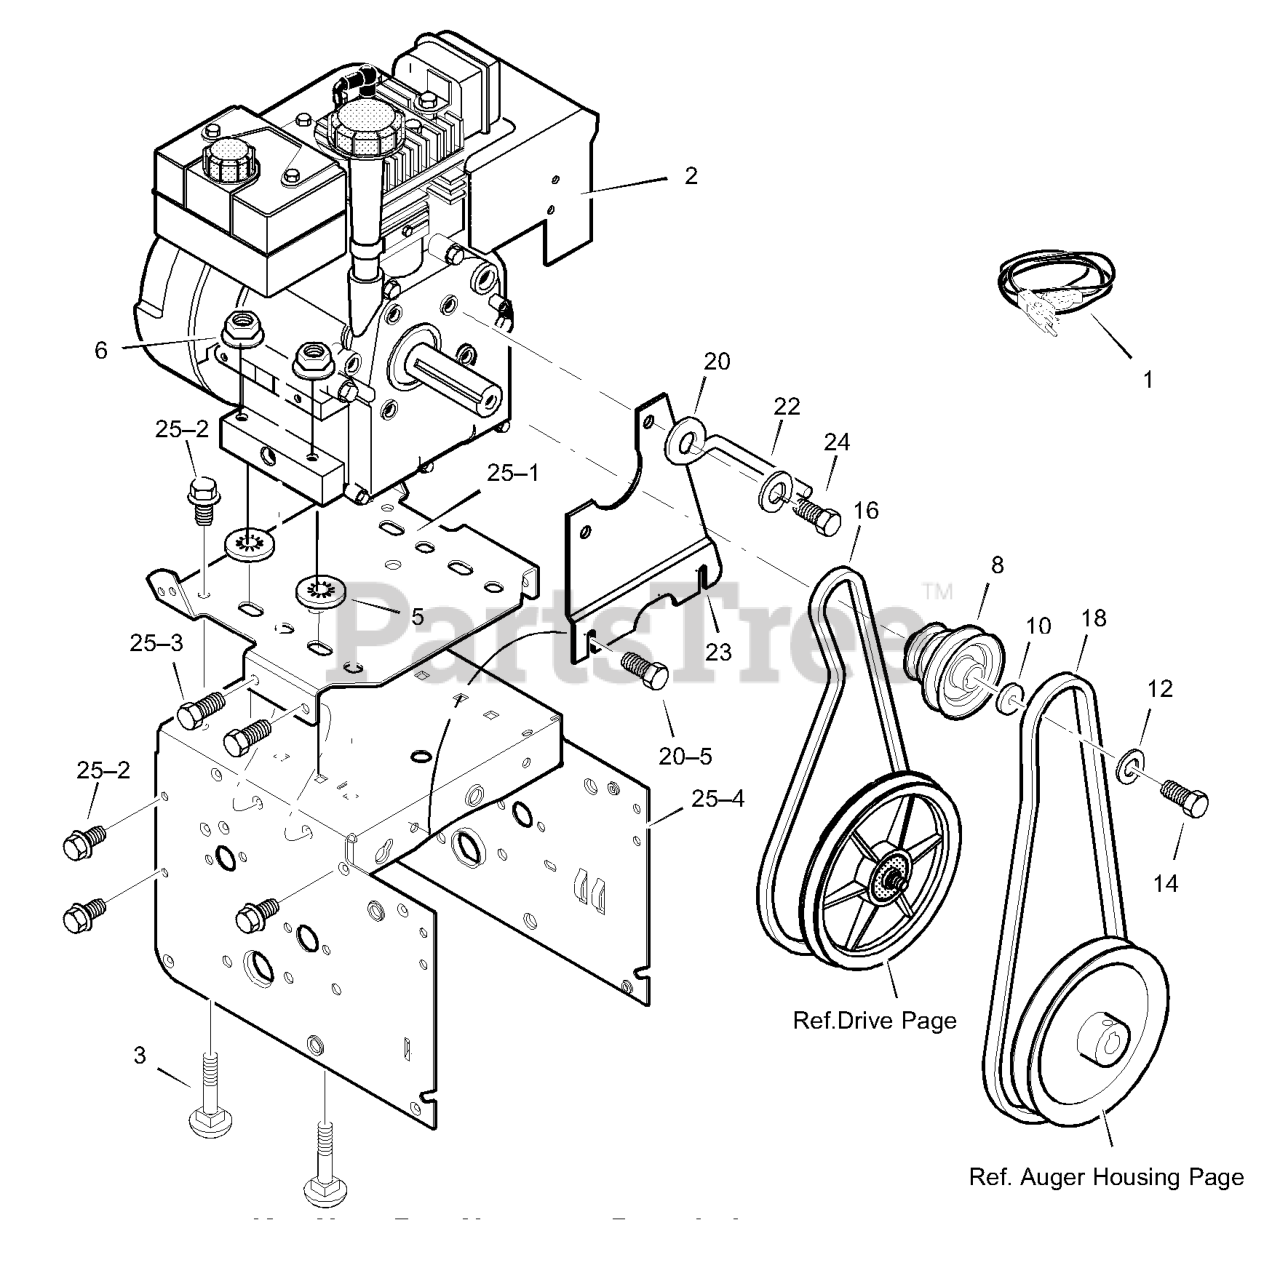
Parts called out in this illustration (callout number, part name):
1	CORD, STARTER MOTOR 220V
2	ENGINE
3	BOLT, CARRIAGE 5/16-18
5	RETAINER, PUSH
6	NUT, HEX 5/16-18
8	PULLEY, ENGINE
10	WASHER
12	WASHER .38ID
14	SCREW, 3/8-24 x 1.00
16	BELT, V 3L 33.13LG
18	BELT, V 4L 38.1MF16" 5-10
20	GUIDE, BELT
22	WASHER, SPTLK .31X.58X.08
23	PLATE, ANTI VIBRATION
24	SCREW, 5/16-24 x 1.00
25	FRAME ASSEMBLY
25-1	PLATE, ENGINE MOUNT
25-2	SCREW, TAP 1/4-20 X .63
25-3	SCREW, TAP 5/16-18 X .50
25-4	FRAME, MOTOR BOX
